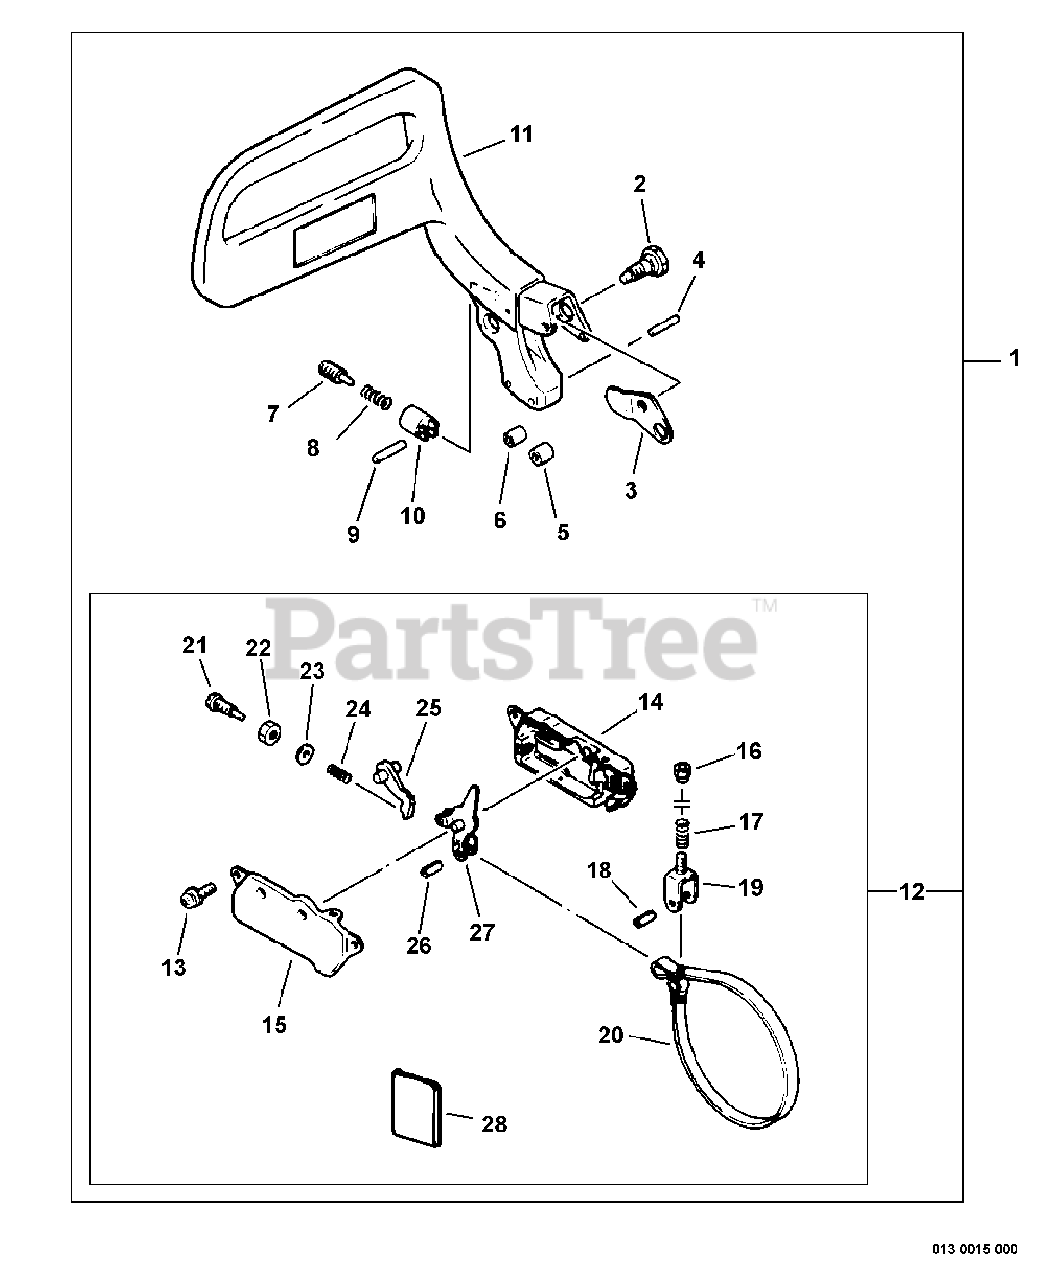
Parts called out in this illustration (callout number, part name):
1	CHAIN BRAKE ASSY
1	CHAIN BRAKE ASSY - ORANGE
6	SPACER
11	LEVER, BRAKE
11	LEVER, BRAKE - BLACK
12	CHAIN BRAKE ASSY
13	SCREW - 4X10
14	COVER, BRAKE
15	COVER, BRAKE
18	PIN - SPRING
19	ADJUSTER, BRAKE BAND
20	BAND, BRAKE
24	SPRING, BRAKE
25	STOPPER, BRAKE
26	PIN - SPRING
27	LEVER, BRAKE
